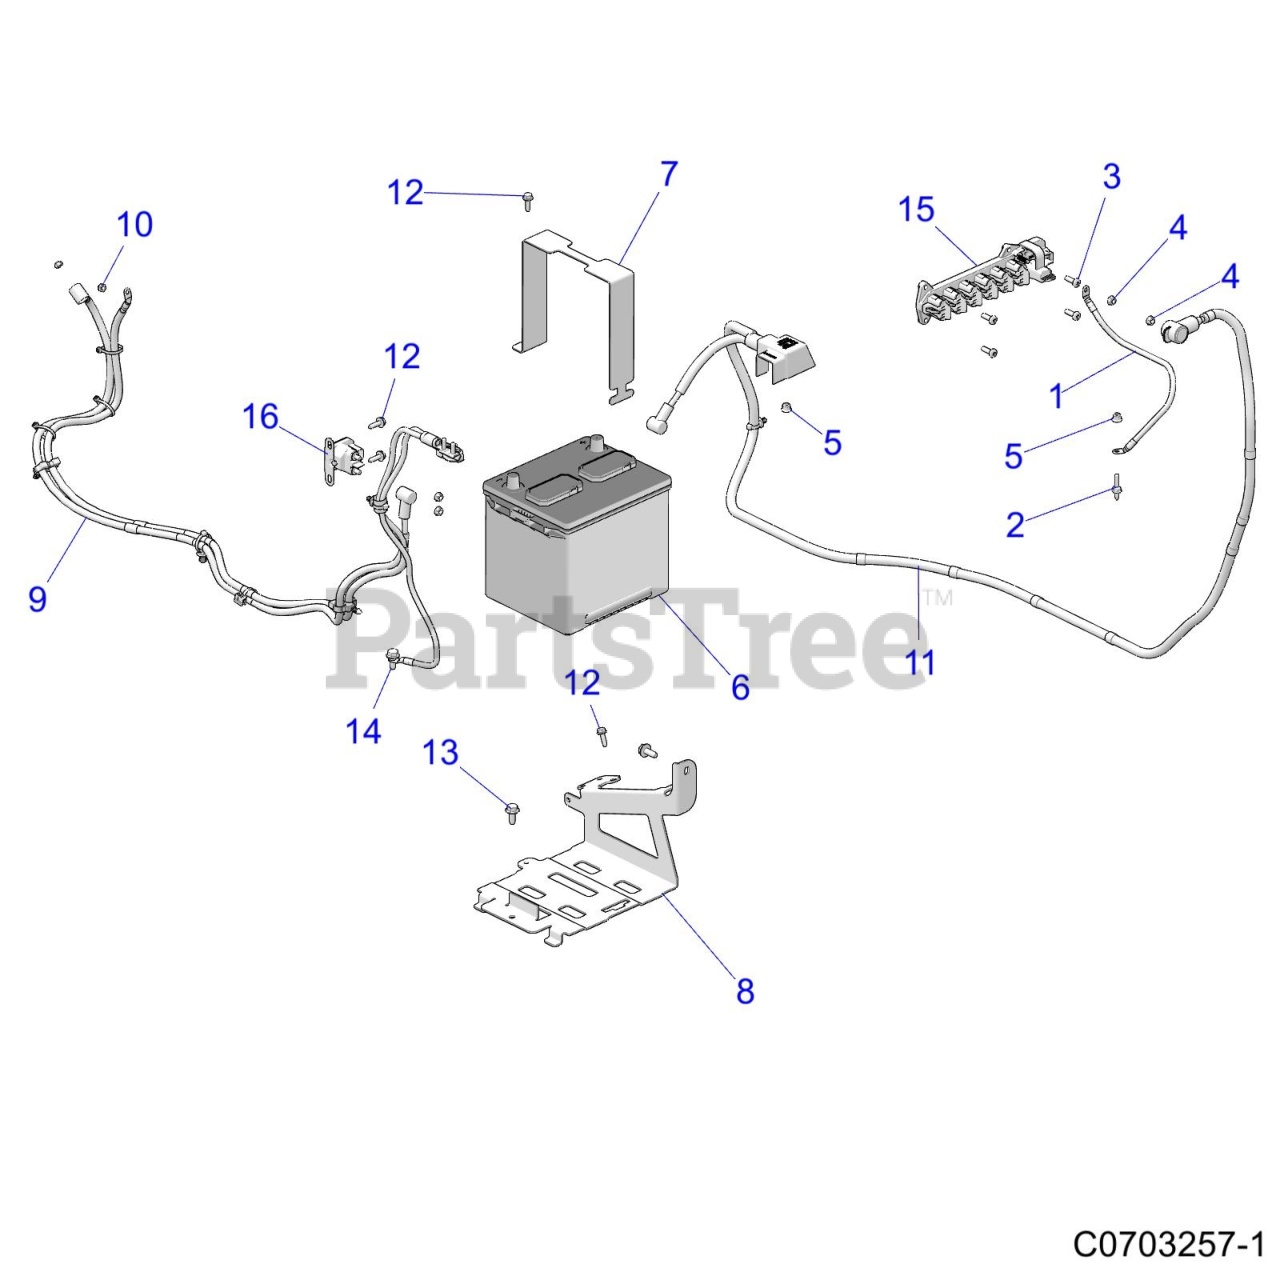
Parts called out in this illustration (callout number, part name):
1	CABLE-BAT TO GND
2	STUD-M6X1.0X19-M6 TAPTITE
3	SCR-TXPH-#14 X .75 HI-LO RIE
4	NUT-HXFLGHD,M6,SERRATED
5	NUT-M6 FLANGE,NYLOK
6	BATTERY-575 CCA,FLOODED,FILLED
7	BRKT-BATTERY STRAP GALV
8	BRKT-BATTERY TRAY,BLK
9	CABLE-START,TO,SOLENOID,GAS
10	NUT,NYLOK(10)
11	CABLE-BATTERY TO SOLENOID
12	SCR-M6X1.0X20,HXHD,FLG,TDFM,BL
13	BOLT-M8X1.25X20,HXFLG,TAP/R-OD
14	SCR-HXFL-M8X1.25X20 TAP ZY3
15	BLOCK-TERMINAL,3 POS
15	FUSE-CARTRIDGE,25A
15	COVER,TB,25A,JCASE
16	SOLENOID-STARTER,SEALED
